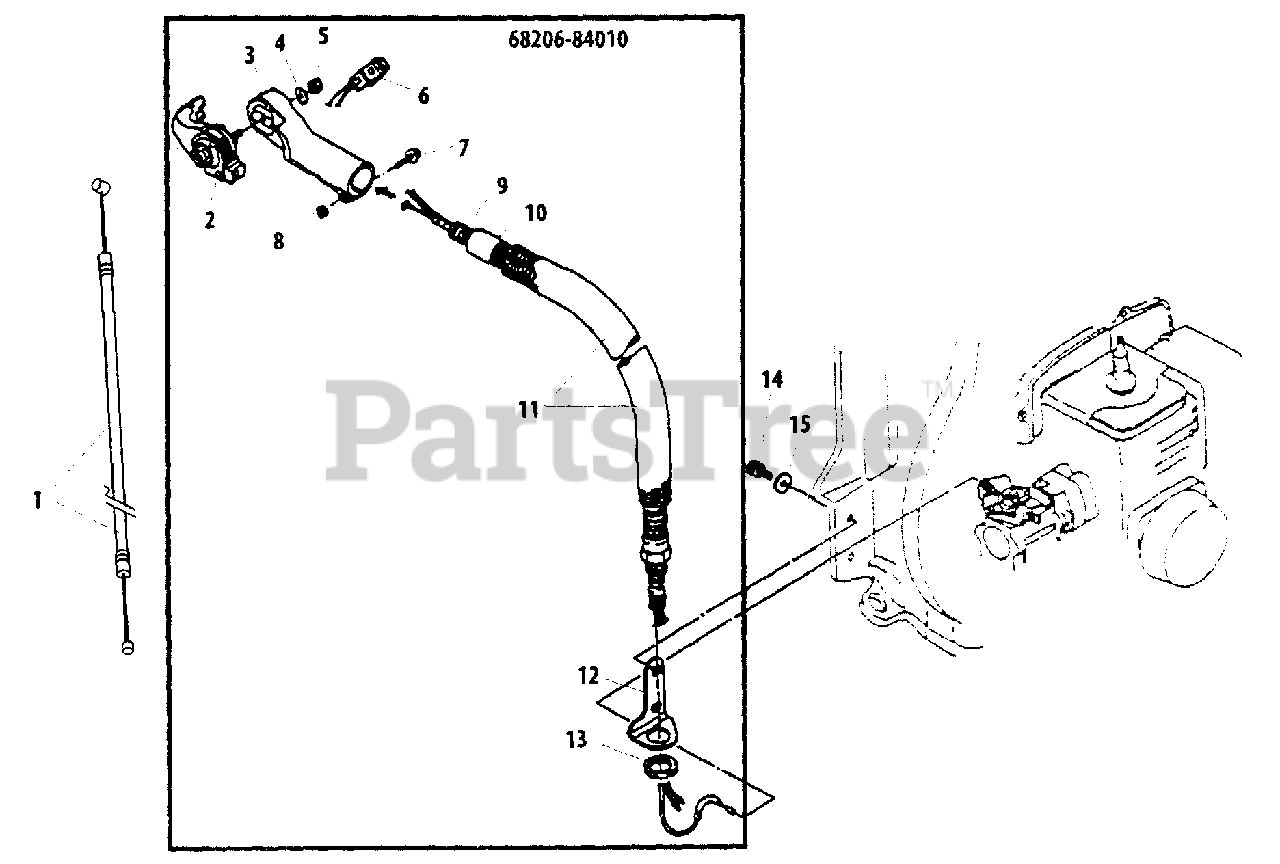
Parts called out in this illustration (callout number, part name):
1	CABLE, THROTTLE
2	THROTTLE LEVER ASSY
3	GRIP
4	WASHER - 5
5	NUT - 5
6	IGNITION SWITCH ASSY
7	SCREW - 5X20
8	NUT - 5
9	FLEX TUBE
10	FLEXIBLE TUBE, METALLIC
11	TUBE, PROTECTIVE
12	BRACKET
13	NUT - 21
14	SCREW - 5X14
15	COLLAR
68206-84010	THROTTLE LEVER ASSY
